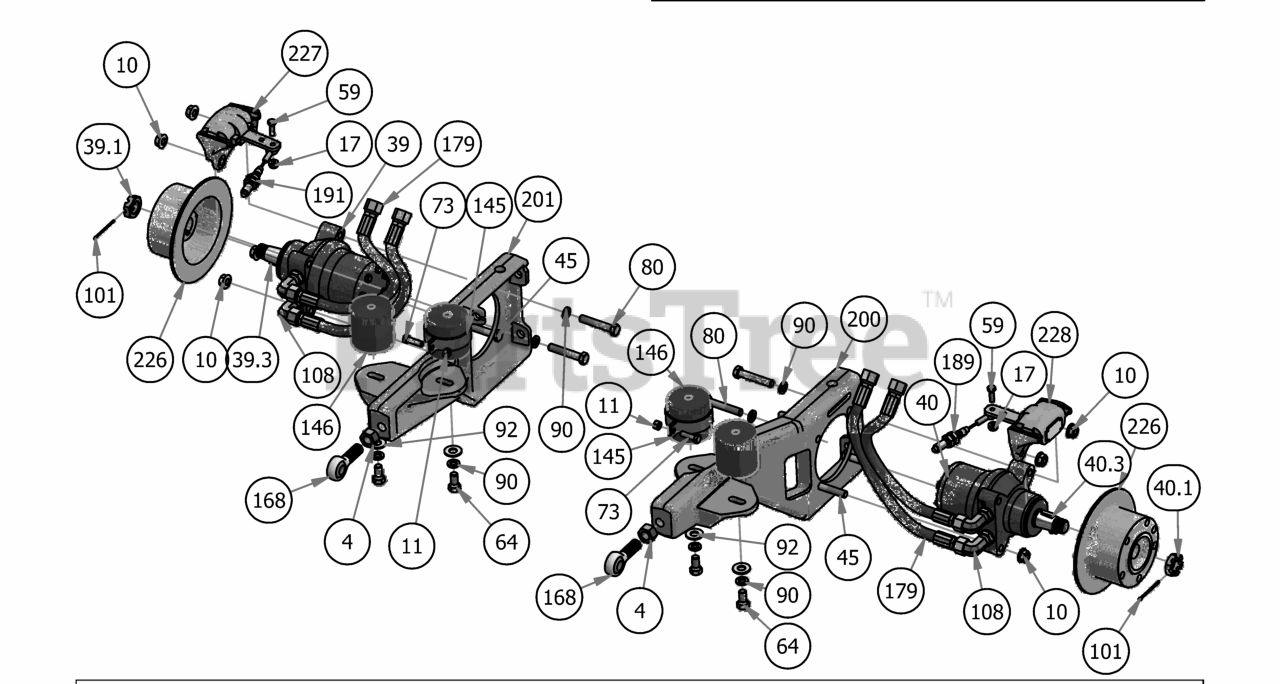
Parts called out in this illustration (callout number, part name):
4	3/4"-16 Fine Full Nut
5	3/4" Course Thread Nylon Lock Nut
10	1/2" Flange Nut
11	3/8" Hex Nut
13	1/2" Hex Nut
14	5/8 Std NC Nylock Nut
17	5/16-18 Nylon Flange Nut
39	18cc Parker Wheel Motor- Right
39.1	1" Castle Nut for Wheel Motor
39.3	Woodruff Key
40	18cc Parker Wheel Motor- Left
40.1	1" Castle Nut for Wheel Motor
40.3	Woodruff Key
45	1/2" x 3" Hex Bolt
46	M6-1.0 X 16MM Hex Bolt
50	3/4 x 2 1/2 Course Thread Bolt
51	AS 2465 - 5/8 x 2 3/4 UNC
57	All Thread-Pump Idler Tensioner
59	5/16" x 1" Bolt
64	1/2" x 1" Hex Bolt
69	1/2" Nylcock Nut (1/2 Jam)
73	3/8" x 1 1/4" Hex Bolt
79	3/8 x 1.5" Bolt
80	1/2" x 2 3/4" Hex Bolt
82	5/8" x 2 1/2" Grade 5 Hex Bolt (Coarse)
84	1/2-20 x 1-1/2 Lug Bolts Zinc
88	5/8" Flat Washer SAE Spec Grade 8
89	1/4" Lock Washer
90	1/2" Lock Washer
91	3/8" Lock Washer
92	1/2" Washer (Grade 8)
95	1/4" Flat Washer
97	5/16" Flat Washer
101	1/8x2-1/4 cotter pin Zinc
103	2019 Assy-26x12-12 Reaper Turf -10.5" Rim
104	2019 Assy-26x12-12 Reaper Turf-8.5" Rim
106	ZT Fitting, 3/8 x 3/8 45 Degree, 4603-6-6
107	2019 Outlaw 45 Degree Pump Fitting #6802-10-08
108	2019 Rouge/Renegade Wheel Motor 90* Fitting #6801-10L
109	90 Degree Fitting, 1/2 x 3/4, 4601-8-8
114	Spacer 1.125OD x .625 ID x .250 Length
116	5/8" x 1/" Collar W/One Set Screw
145	2019 Bad Boy Max Iso-Band
146	Vibration Mount-Green Dot
148	5" Pump Pulley
151	Deck Idler Spring
153	2019 Rogue Pump Idler Assy
154	2019 Suspension Gusset Outlaw
158	5mm x 1.25" Key
165	2019 Suspension Link Body
166	2019 RH 5/8" Heim
167	2019 LH 5/8" Heim
168	3/4-16 RH Male Rod End
169	2019 Rogue/Renegade Left Pump 16cc
170	2019 Rogue/Renegade Right Pump 16cc
179	20" Hydraulic Hose
189	2019 Short Brake Cable-Suspension Models
191	2019 Long Brake Cable-Renegade, Rogue
200	2019 Left Trailing Arm
201	2019 Right Trailing Arm
204	2019 Veritical Suspension Frame
226	Brake Disk
227	XP/AOS Right Brake Caliper
228	XP/AOS Left Brake Caliper
